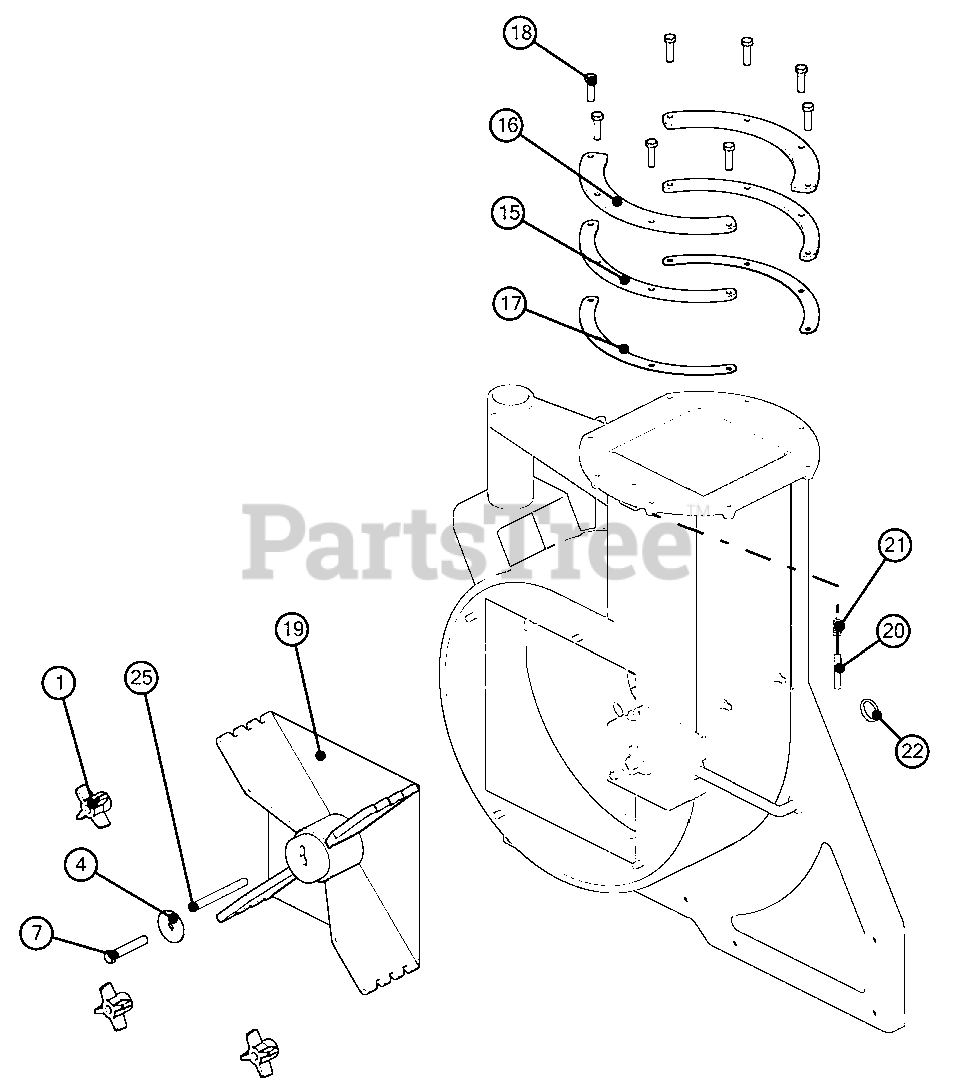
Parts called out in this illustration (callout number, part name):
1	KNOB- 5/16 THRD
4	WASHER AREA VAC 35 29/64X 13/4X
7	BLT HEX .38-24 X 2.5 GR5 YZ EP80
15	SPACER, FLANGE
16	FLANGE, TOP
17	SPACER, FLANGE .060
18	BLT HEX .31-18 X 1.25 GR5 YWZC
19	FAN WLDT 20 TL
20	PIN, SPRING LATCH
21	SG-COMP .028X.34X1.062 WLD75
22	RING, LOCKING
25	KEY-SQ .250 X 4.00
